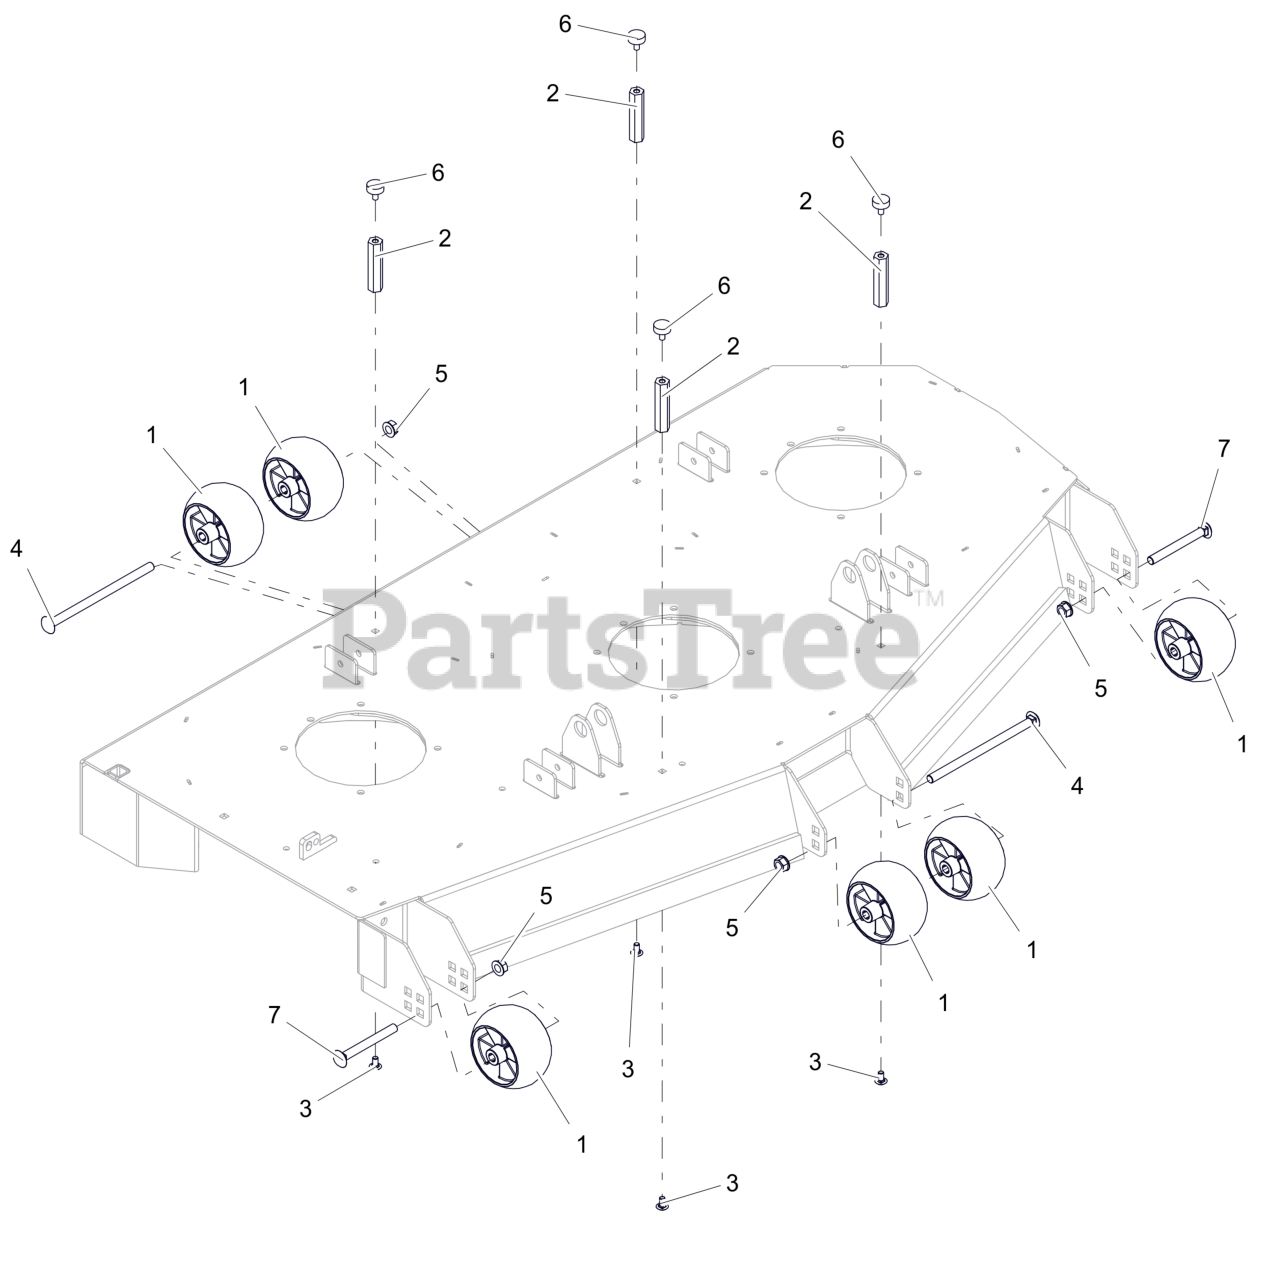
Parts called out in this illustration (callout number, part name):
1	WHEEL, ANTI SCALP - 5X3 CTR W/RIBS
2	NUT, COUPLING .312-18 X 3.375
3	BTL,RHSSN .313-18 X 0.625 G5 ZCC
4	BTL,RHSN .500-13 X 8.5S G5 ZCC
5	NUT-LK-CTR-FLG .500-13 GG ZCC
6	BUMPER, RUBBER
7	BLT,RHSN .50-13X4.50 G5 ZCC
